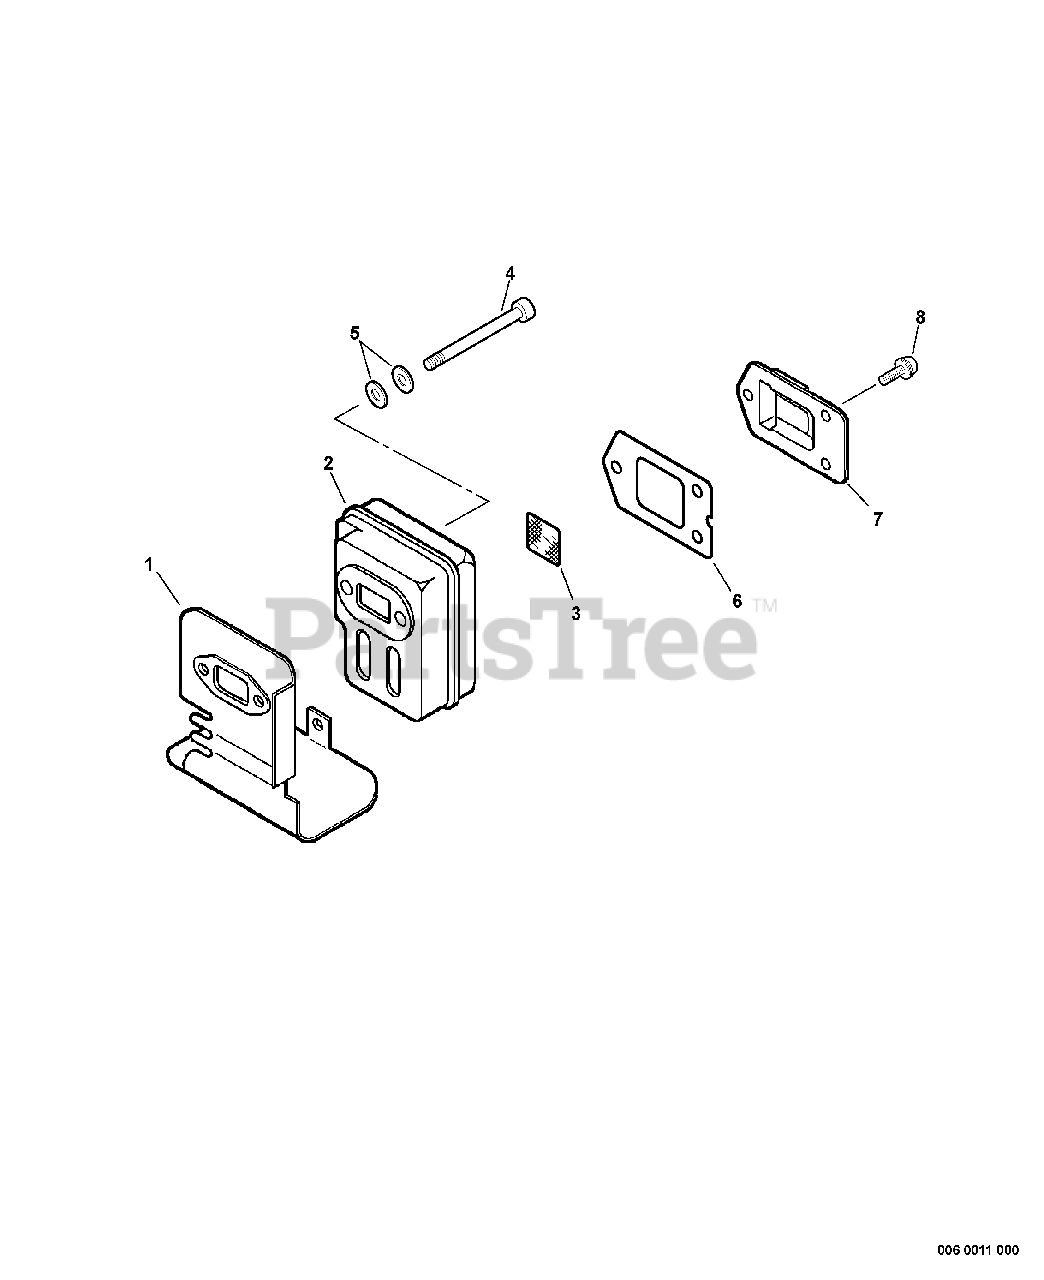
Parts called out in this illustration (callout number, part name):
1	SHIELD, EXHAUST
3	SCREEN, SPARK ARRESTOR
4	SCREW - 5X55
5	WASHER - 5
6	GASKET, EXHAUST
7	GUIDE, EXHAUST
8	SCREW - 4X10
